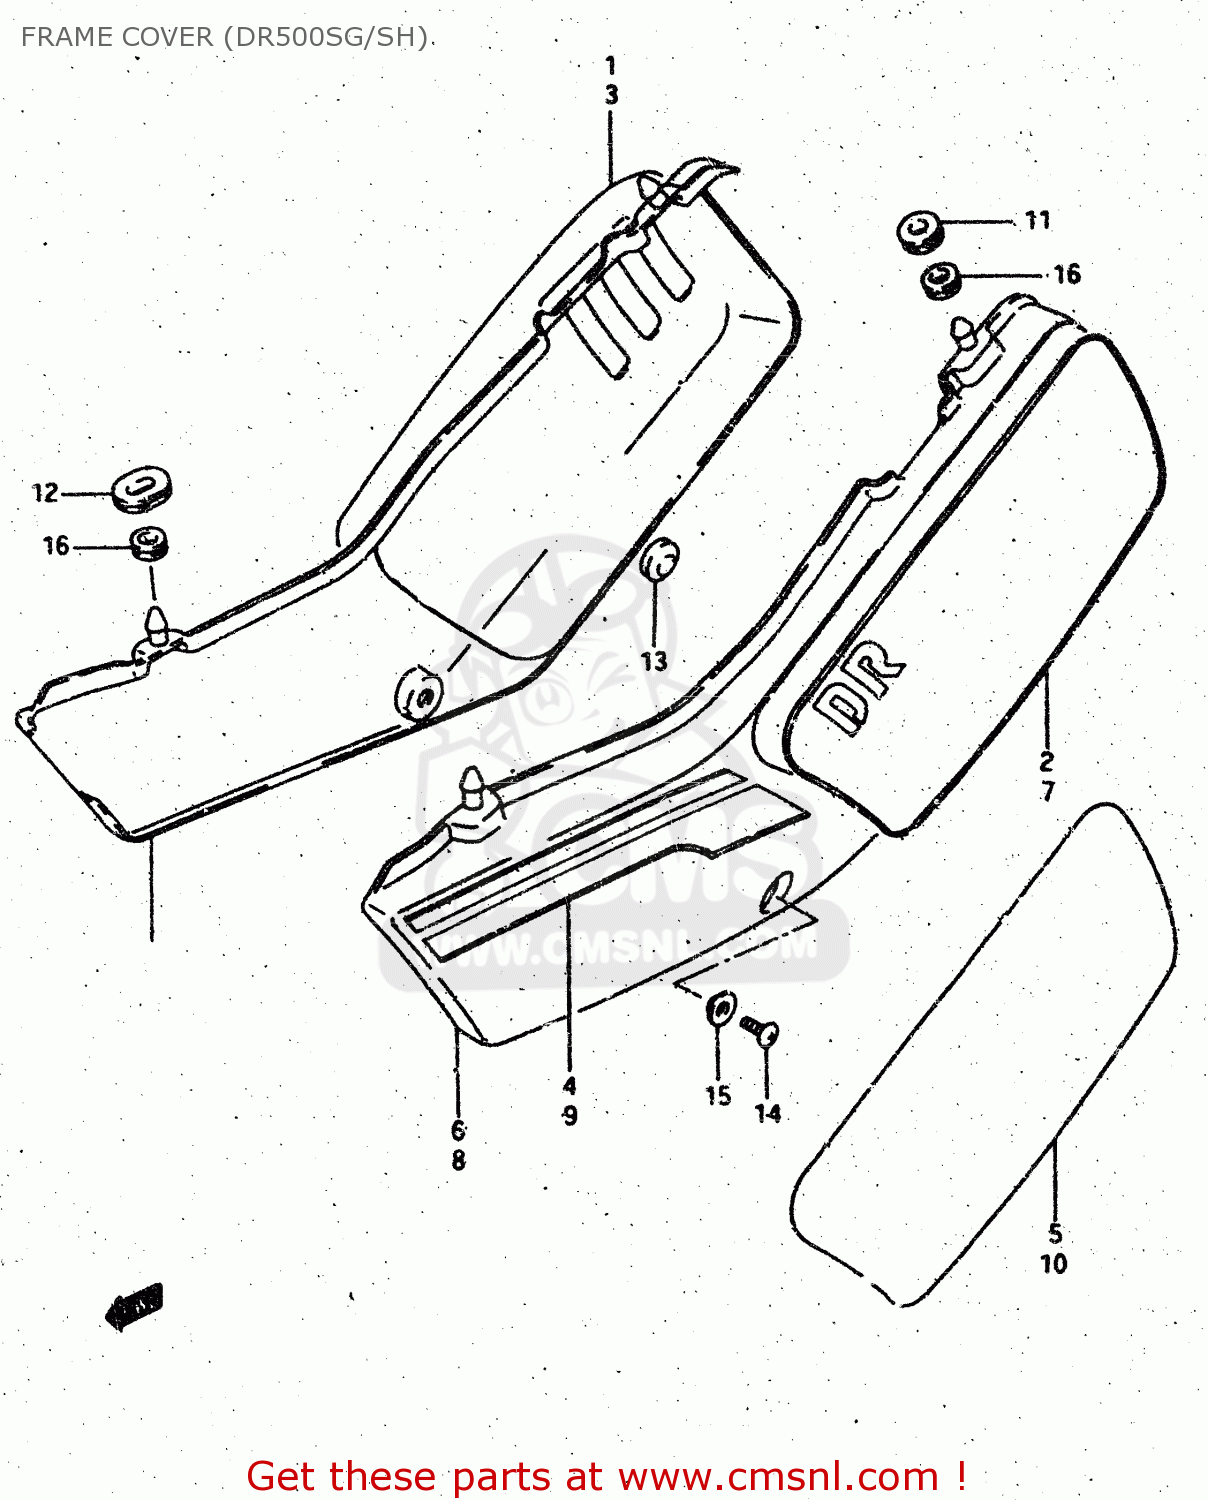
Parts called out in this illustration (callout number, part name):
1	COVER,FRAME RH
2	TAPE SET, SIDE COVER RH
3	COVER, SIDE RH (BLUE)
4	TAPE SET, SIDE COVER RH
5	TAPE, REAR RH (BLUE)
6	COVER,FRAME,LEFT
7	TAPE SET, SIDE COVER LH
8	COVER, SIDE LH (BLUE)
9	TAPE SET, SIDE COVER LH
10	TAPE, REAR LH (BLUE)
11	CUSHION
12	CUSHION
13	CUSHION
14	SCREW 6X12
15	WASHER
16	CUSHION,SIDE COVER BOSS
